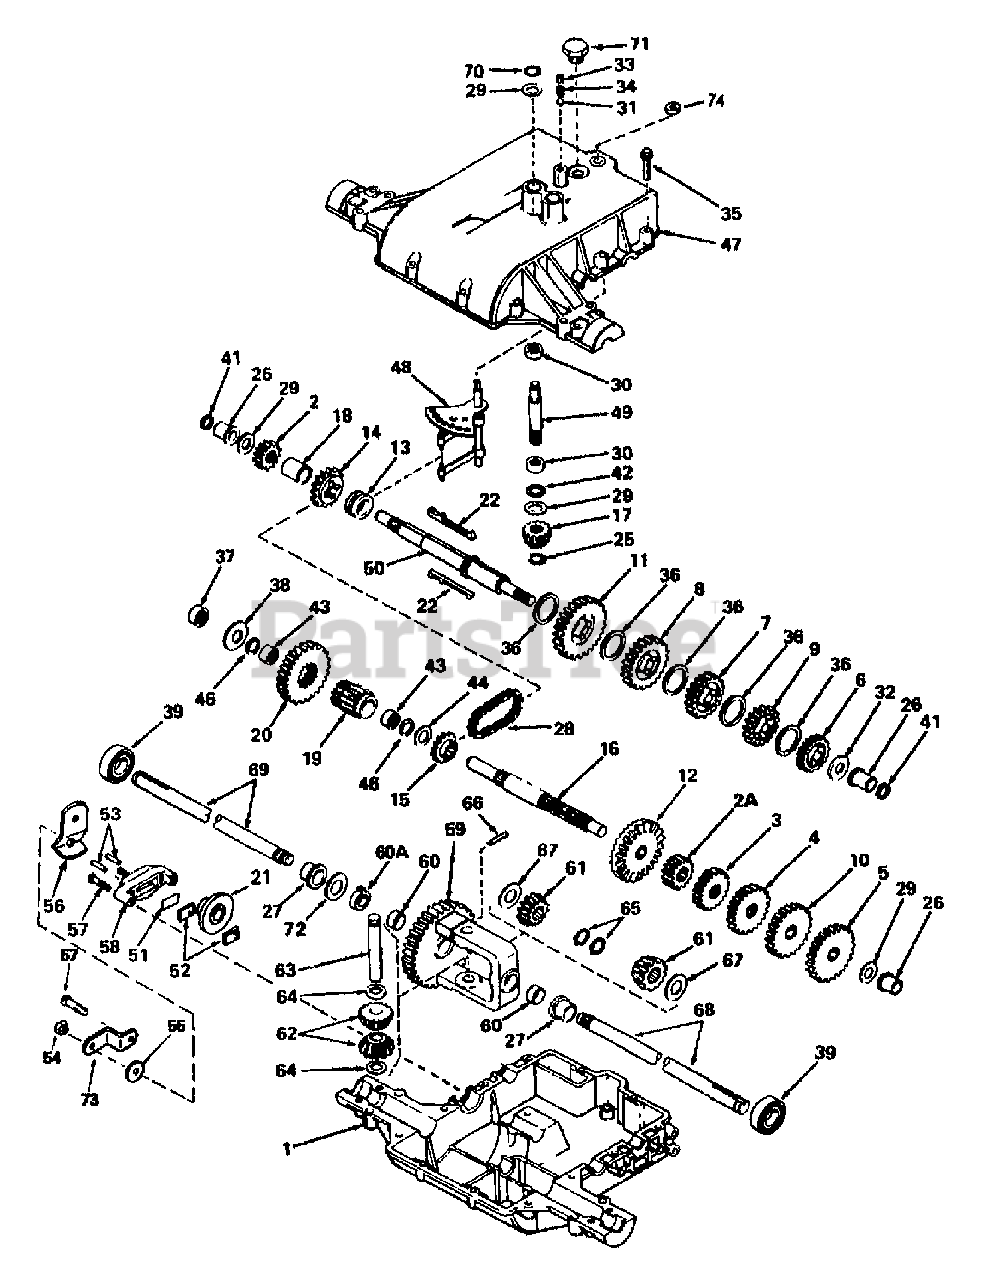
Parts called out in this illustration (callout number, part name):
1	TRANSAXLE CASE
2	SPUR GEAR
2A	SPUR GEAR
3	SPUR GEAR
4	SPUR GEAR
6	SPUR GEAR
7	SPUR GEAR
8	SPUR GEAR
9	SPUR GEAR
10	SPUR GEAR
11	SPUR GEAR
12	BEVEL GEAR
14	SPROCKET
15	SPROCKET
16	COUNTERSHAFT
17	INPUT PINION
19	OUTPUT GEAR
20	OUTPUT GEAR
21	BRAKE DISK
22	SHIFT KEY
25	RET RING
26	BUSHING
28	ROLLER CHAIN
29	WASHER
30	NEEDLE BEARING
34	SPRING
36	WASHER
37	BALL BEARING
39	BALL BEARING
43	NEEDLE BEARING
46	SQUARE CUT RING
48	ROD & FORK
49	INPUT SHAFT
50	BRAKE SHAFT
51	BRAKE PAD PLATE
52	BRAKE PAD
53	DOWEL PIN
56	BRAKE LEVER
59	DIFF GEAR ASSY
61	BEVEL GEAR
62	BEVEL GEAR
63	DRIVE PIN
65	RET RING
66	ROLL PIN
70	RET RING
